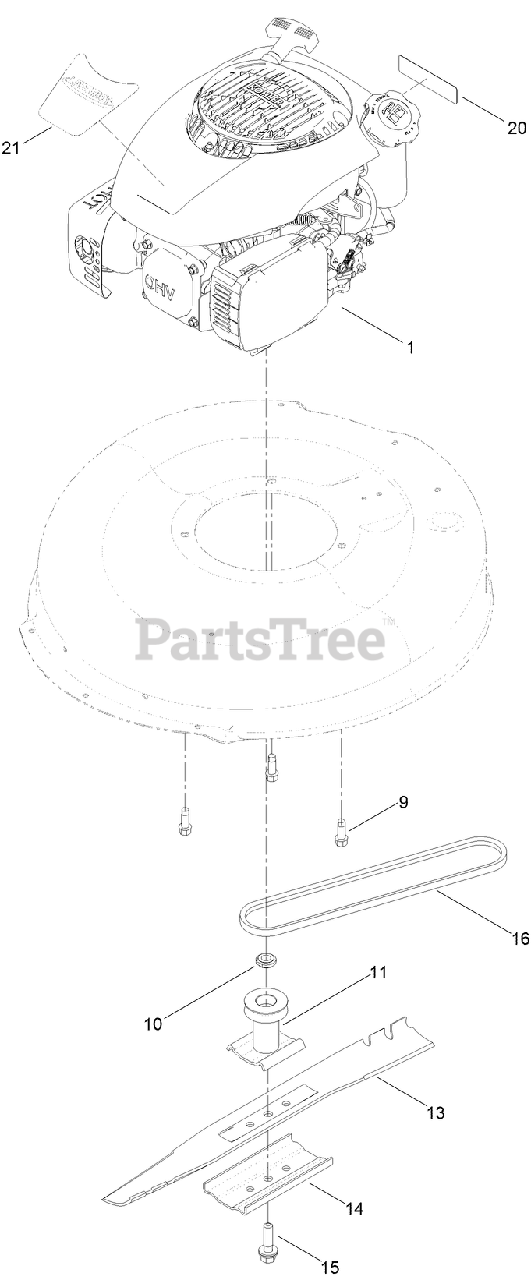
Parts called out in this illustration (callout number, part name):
9	SCREW-TAPTITE
10	SPACER-DRIVER
11	DRIVER-BLADE
14	SUPPORT-BLADE
15	BOLT-BLADE
20	DECAL-ARRESTER, SPARK
